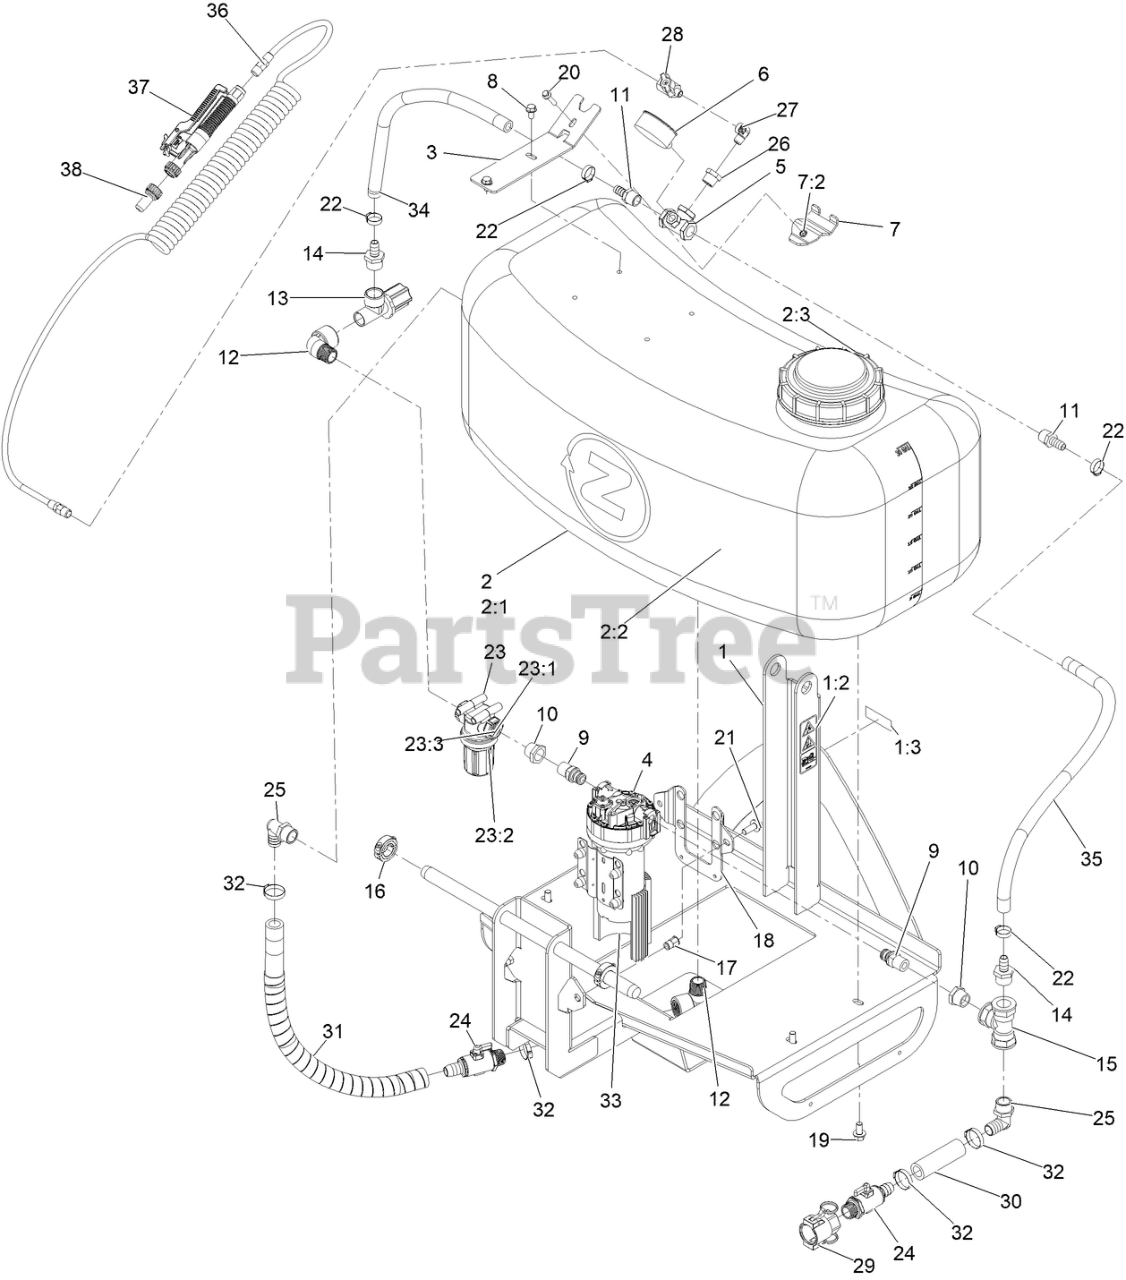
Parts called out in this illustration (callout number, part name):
1	30 Gal Base ASM W/Decals
1:2	DECAL-STORED ENERGY ATTACHMENT
1:3	DECAL-WARNING
2	ASM-TANK, 30 GAL
2:1	TANK-CENTER, 30 GAL
2:2	Fitting-Bulkhead
2:3	CAP-TANK, SPRAY
3	Plate-Pump Mnt, 30 Gal Attach
4	PUMP-5.3 GPM
5	FITTING-CROSS
6	GAUGE-PLAIN
7	Brkt-Tee Mount
7:2	Nut-Clinch, Hex
8	SCREW-HHF
9	PUMP FTG X 1/2MPT FQ5MS-1
10	REDUCER-BUSHING, PLASTIC
11	FITTING-HOSEBARB
12	ELBOW-90DEG
13	VALVE-THROTTLE
14	FITTING-STRAIGHT
15	FITTING-TEE
16	Collar-Shaft, Split, Cz
17	NUT-CLINCH,HEX
18	BRACKET-MOUNT, PUMP
19	Screw-HH Flg 3/8-16 X 3/4
20	SCREW-HHF
21	SCREW-HHF 3/8-16 X 1
22	CLAMP-OETIKER, 167
23	STRAINER-T, 50 MESH
23:1	Gasket-Strainer
23:2	SCREEN-50 MESH
23:3	BOWL-STRAINER, BLACK
25	FITTING-ELBOW, 90
26	FITTING-REDUCER
27	FITTING-ELBOW, 90
28	VALVE-CHROME, 1/4
29	COUPLER-FEMALE
30	HOSE-SPRAY
31	HOSE-SPRAY, WRAPPED
32	Clamp-Oetiker, 167
33	HEATSINK-3.0""
34	Hose-Spray, Wrapped
35	Hose-Epdm
36	HOSE-COILED, 15 FT
37	GUN-SPRAY, SPOT
38	TIP-SPRAY, #12 SPOT
